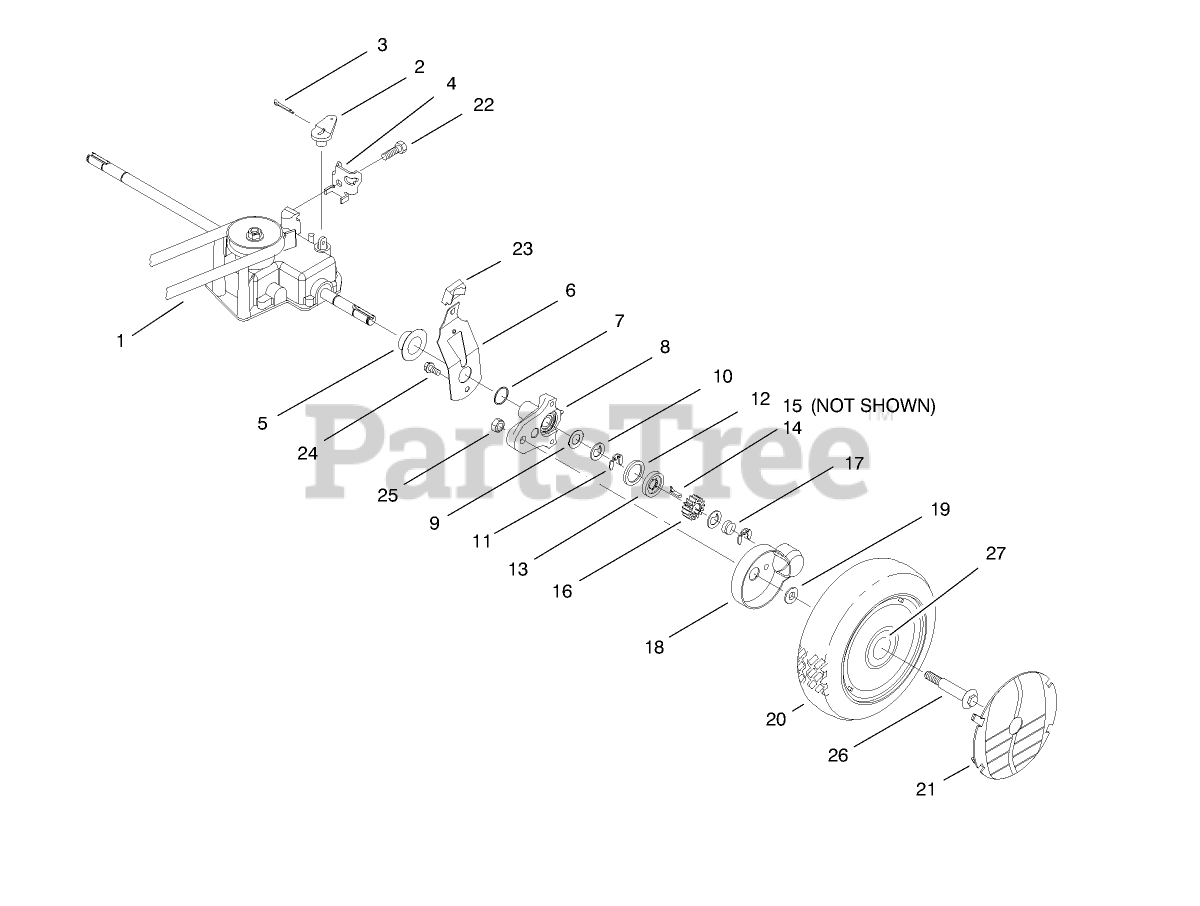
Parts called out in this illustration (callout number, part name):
1	V-BELT
2	LEVER-SHIFT
3	PIN-COTTER
4	CLAMP-CABLE
5	CAP-END
6	SPRING ARM ASM
7	O-RING
9	WASHER-ARM, PIVOT
10	WASHER-THRUST, KEYED
11	RING-RETAINING,CLIP
12	RING-FRICTION
13	WASHER-CLUTCH
14	KEY-ROCKING, LH
15	KEY-ROCKING, RH
16	GEAR-PINION
17	SPRING-COMPRESSION
18	COVER-WHEEL
19	SPACER-COVER, WHEEL
20	WHEEL AND TIRE ASM
22	SCREW-HWHTF
23	KNOB-ARM
24	SCREW-HWH
25	NUT-LOCK
27	BUSHING
